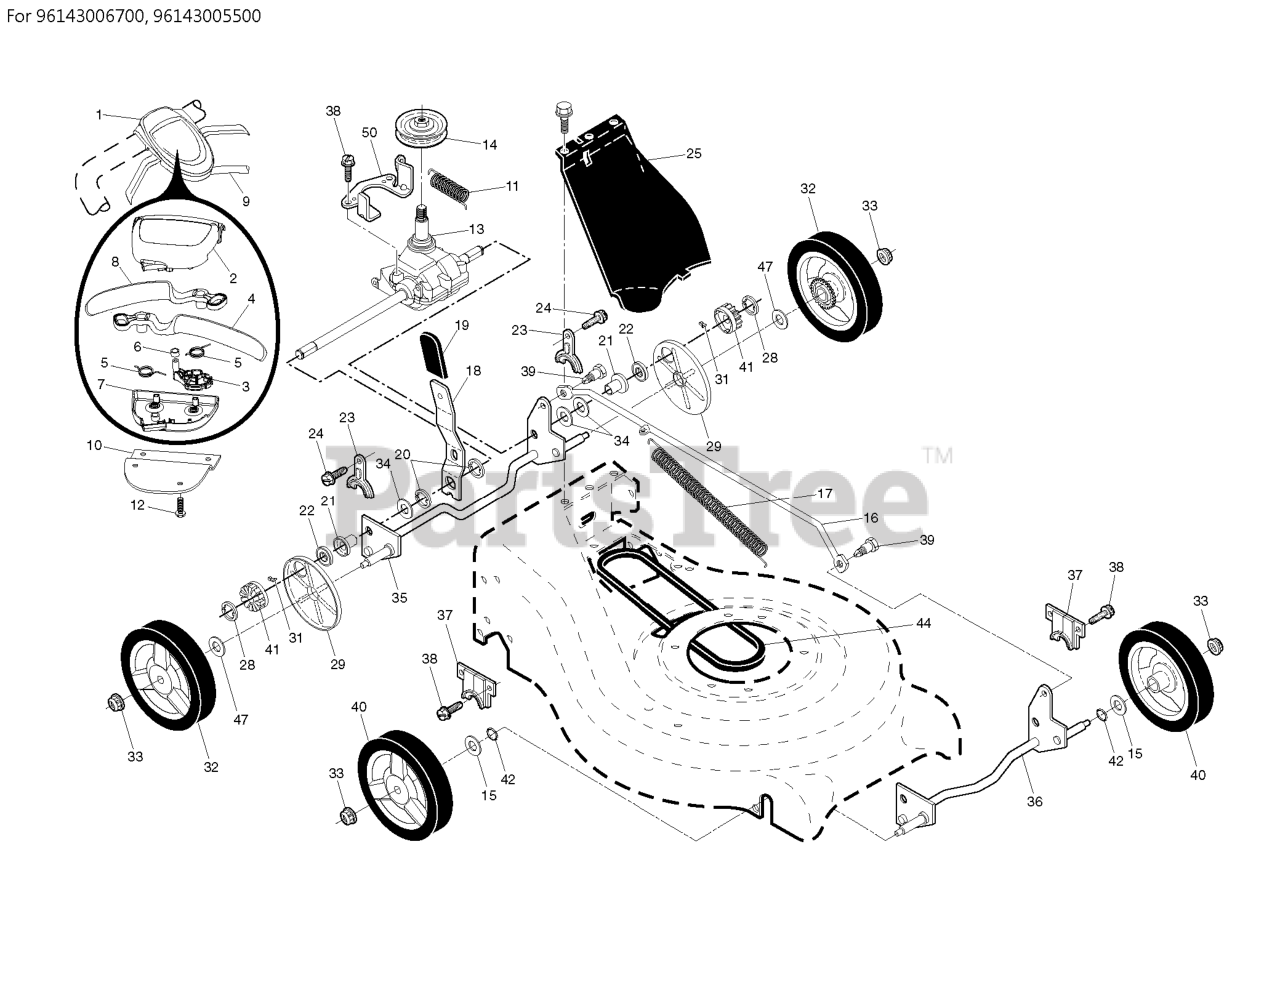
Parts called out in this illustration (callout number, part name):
1	RP.CONTROL.AW2.21RGD
2	RP CASE.CONT.ROL.TOP.HUSQV.
3	CAM.GEN2.DUAL.TRIGGER
4	LEVER.CONTROL.LH.22+.CURVE.BLA
5	SPRING, DRIVE CONTROL
6	BUSHING.CONTROL.CAM
7	COVER.DR.CONTROL.LOWER.GRAY
8	LEVER.CONTROL.RH.22+.CURV.BLAC
9	CABLE.CONTROL.21RGD
10	BRACKET.DRIVE.CONTR.GEN2.BLACK
12	SCREW, PHILLIPS HEAD 10 X 5/8
13	TRANSMISSION.21.RWGD
14	PULLEY.1.PIECE
15	WASHER.FLAT.1/2
16	ROD.CONNECTING.SPT.BLACK
17	SPRING EXTENSION
18	SPRING.SELECTOR.
19	KNOB.EXT.ERGO.BLACK
21	BEARING SUPPORT
22	BEARING
23	BRACKET
24	SCREW 14-20 X 5/8
25	COVER.DR.ASM.199775X418.CE
28	E-RING 7/16 RE
29	COVER.DUST.WHEEL
31	PAWL, DRIVE
32	WHEEL & TIRE ASSY, REAR
33	NUT.HEX.FLANGE.3/8-16.LO(3 2)
35	SHAFT ASSY REAR
36	SHAFT ASSY, FRONT
37	RETAINER.FRONT.SHAFT
39	SHOULDER BOLT SEMI GIMLET PT.
40	WHEEL & TIRES ASSY, FRONT
41	PINIION.14.TOOTH.RGD
42	O-RING..070X.487.NEOPRENE
44	BELT.RGD.VS
47	WASHER FLUT
50	BELT KEEPER
